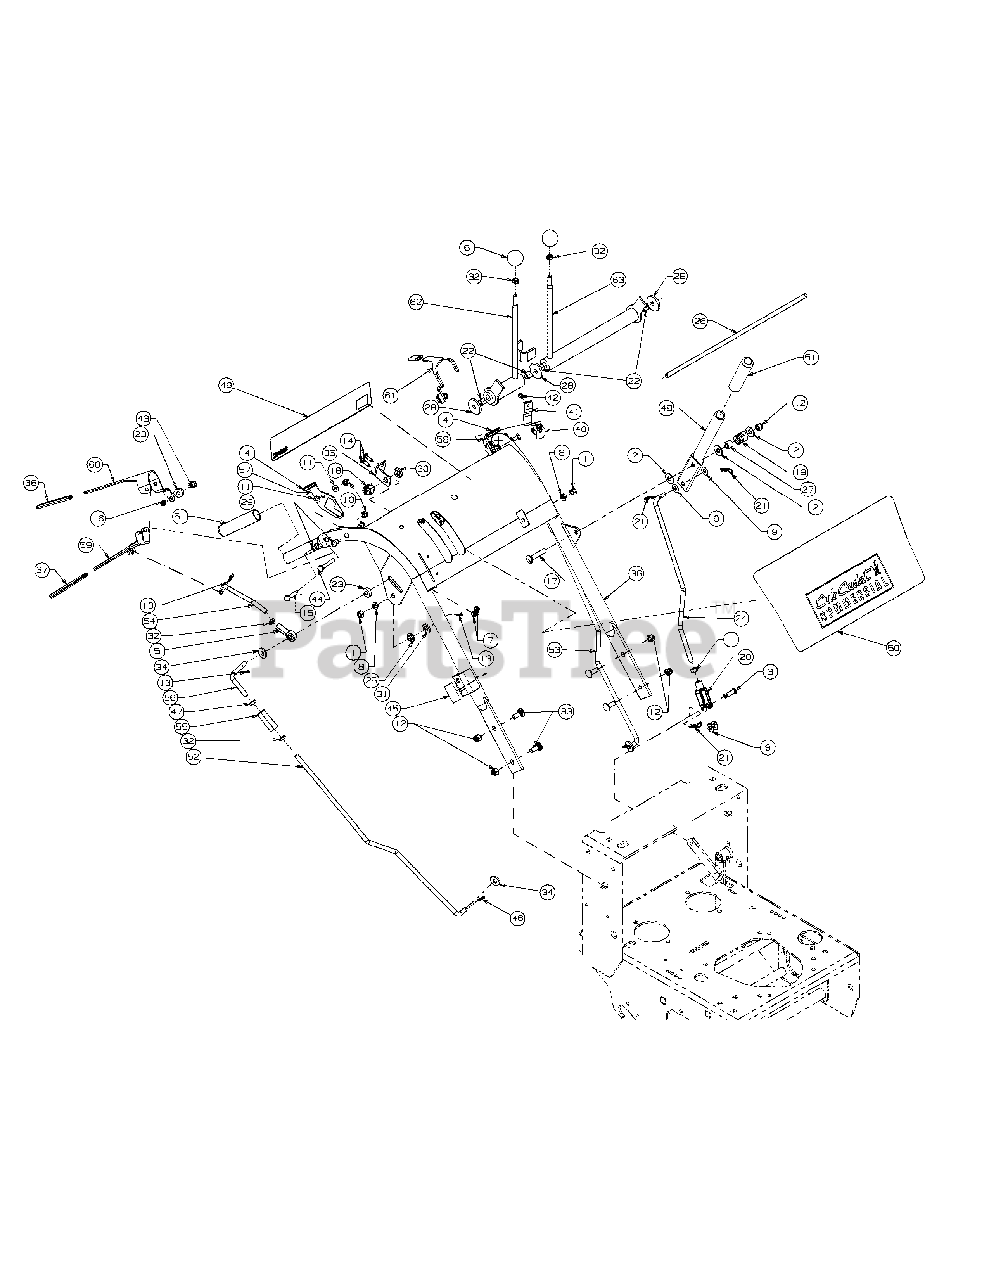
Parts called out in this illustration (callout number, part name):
1	Hex Nut, 3/8 - 16
2	Flat Washer, SS, 3/8
3	Clevis Pin, 3/8 x 1 1/8
4	Grip, 1.25, Black Neutral Lock
5	End Rod, 3/8, Female
6	Knob, 1-3/8 x 1-19/64, 3/8-24
7	Lock Nut, Nylon Insert, 1/4-20
8	Lock Washer, 3/8 Zinc
9	Flat Washer, 3/8, SAE
10	Nut, 5/16-18
11	Flat Washer, SAE 5/16
12	Lock Nut, Nylon Insert, 3/8-16
13	Cotter Pin, 5/32 x 1-1/2 Zinc
14	HHCS, 1/4-20, .75
15	HHCS, Standard, 5/16-18 x 2
16	Lock Nut, Nylon Insert, 1/4 - 28
17	Carriage Bolt, 3/8 -16 x 2
18	Switch Operator’s Presence
19	Spring, .850
20	Yoke, 3/8 - 16, Female
21	Hair Pin, 3/8 - 1/2
22	Bushing, 9/16 OD x 3/8 ID x 1/2
23	Hydro, Spacer Control Rod
24	Blade Clutch, Hydro Rod Base
25	Hydro Bush Control Rod
26	Hydro Rod, Speed Control
27	Sleeve Spring, 32/36/48
28	Friction Washer
29	Nylon Bushing
30	Hex Nut, Dead Man Switch
31	Washer, .469 ID x .875 OD x .105
32	Hex Jam Nut, 3/8-24
33	Carriage Bolt, 3/8 -16 x 2
34	Flat Washer .406 ID x 1.00 OD
35	Mounting Switch, Neutral, Safety
36	Hydro, Handle Assembly
37	Control Sleeve, Drive Black
38	Operators Control Sleeve, Yellow
39	Harness Adapter Assembly
40	Snap Mounting Switch
41	Retension Spring
42	Screw, TT, 10-24, .5
43	Shoulder Screw, .38 x .412, 1/4-28
44	HHCS, 5/16-18, 2.00
45	Parking Brake Decal
46	Cotter Pin Internal, .072 x 1.12
47	Left Hand Threaded Jam Nut, 3/8-24
48	Clutch Lever Blade
49	Lable Handle
50	Panel Label
51	Black Handle Thin Grip
52	Large Right Control Rod
53	Large Left Control Rod
54	Short Control Rod
55	Turnbuckle
56	Upper Control Rod
57	Latch, RH, Neutral Hydro
58	Latch, LH, Neutral Hydro
59	Control Lever Assembly
60	Operator Presence Control Handle, RH
61	Operator Presence Control Handle, LH
62	Control Assembly, Speed Hydro, RH
63	Control Assembly, Speed Hydro, LH
